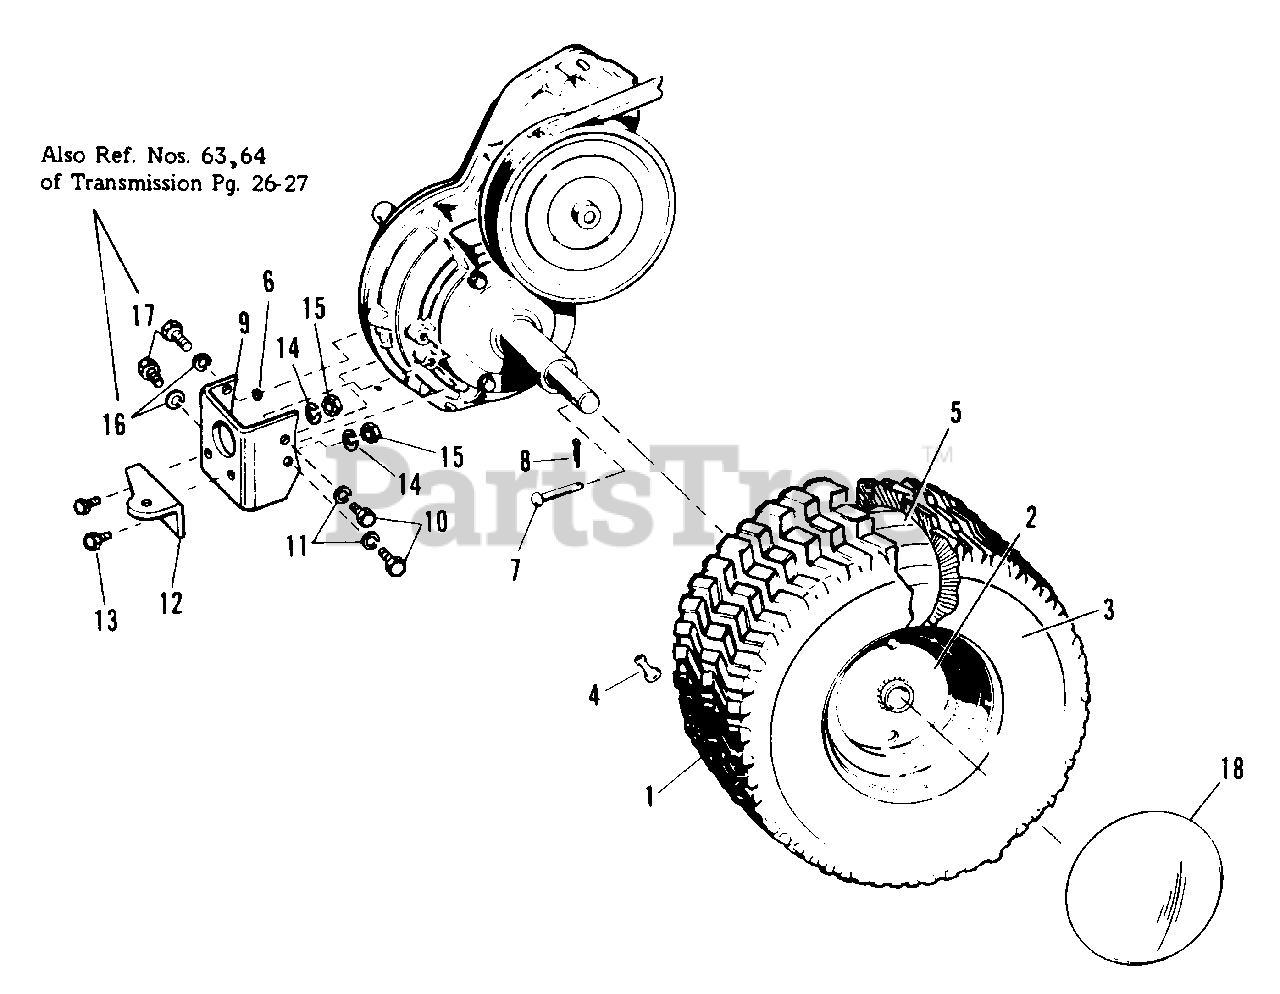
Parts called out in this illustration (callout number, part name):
1	Wheel & Tire Assembly
2	Wheel Assembly
4	Valve Stem and Cap
6	Washer, Plain, 5/16"
7	Pin
8	Pin, Cotter 1/8" x 3/4" lg.
9	Bracket, Draw Bar
10	Capscrew, Hex, 3/8"-16 x 3/4" lg.
11	Lockwasher, 3/8"
12	Clip, Draw Bar Hitch
13	Capscrew, 3/8"-16 x 1" lg.
14	Lockwasher, 3/8"
15	Nut, Hex, Full, 3/8"-16
16	Lockwasher, 5/16"
17	Capscrew, 5/16"-18 x 1-1/2" lg.
18	Cap, Hub, Rear
